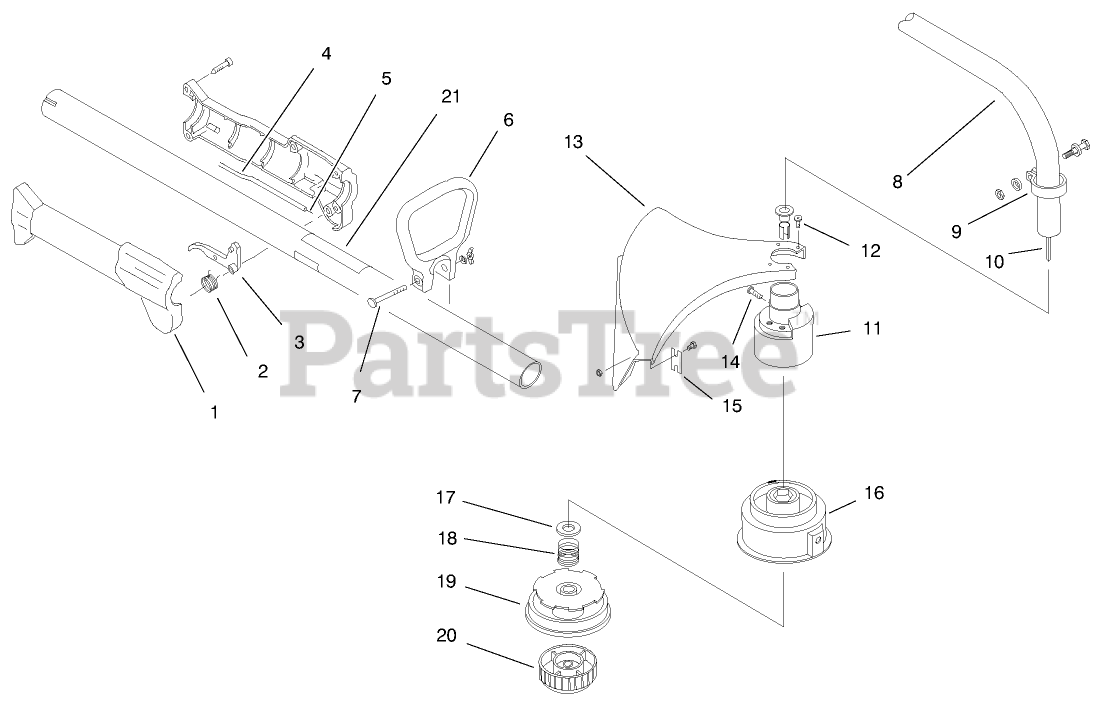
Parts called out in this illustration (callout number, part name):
7	HARDWARE - D-HANDLE
8	DRIVE SHAFT HSG ASM
9	CLAMP ASM - UPPER
10	SHAFT - FLEX, 48.94
11	BUSHING HSG ASM
15	BLADE ASM
16	OUTER SPOOL EYELET ASM
17	RETAINER WASHER
18	SPRING
19	REEL - INNER
20	KNOB ASSEMBLY-SMALL BUMP
